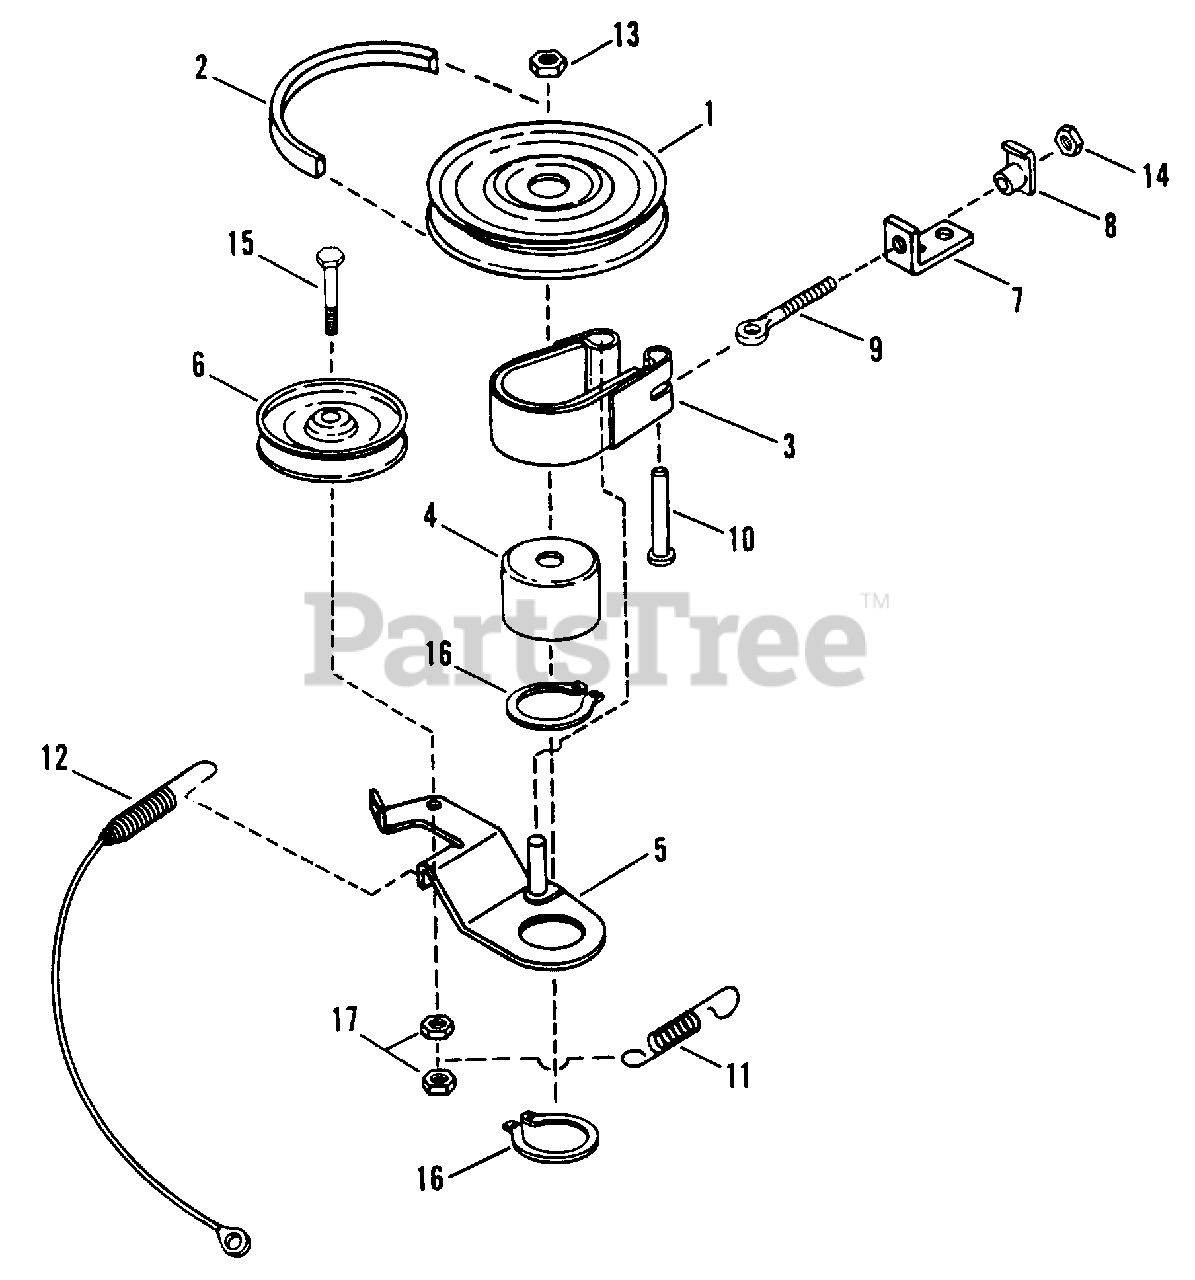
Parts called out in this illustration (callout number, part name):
1	PULLEY, Drive 5.75" OD
2	BELT, Drive VA101
3	BAND, Brake Assembly
4	DRUM, Brake
5	ASSEMBLY, Brake Arm
6	PULLEY, Idler Flat 4.12" OD
7	ANCHOR, Brake
8	TEE-NUT, 1/4-20
9	BOLT, 1/4-20 Eye
10	PIN, Clevis, 1/4 x 1 1/4"
11	SPRING, Blade Brake
12	CABLE, Blade 28.5"
13	NUT, 3/4-16 Hex Jam
14	NUT, 1/4-20 Hex
15	SCREW, 3/8-24 x 2" Hex Hd. Cap
16	RING, 2" External Retaining
17	NUT, 3/8-24 Hex Lock
